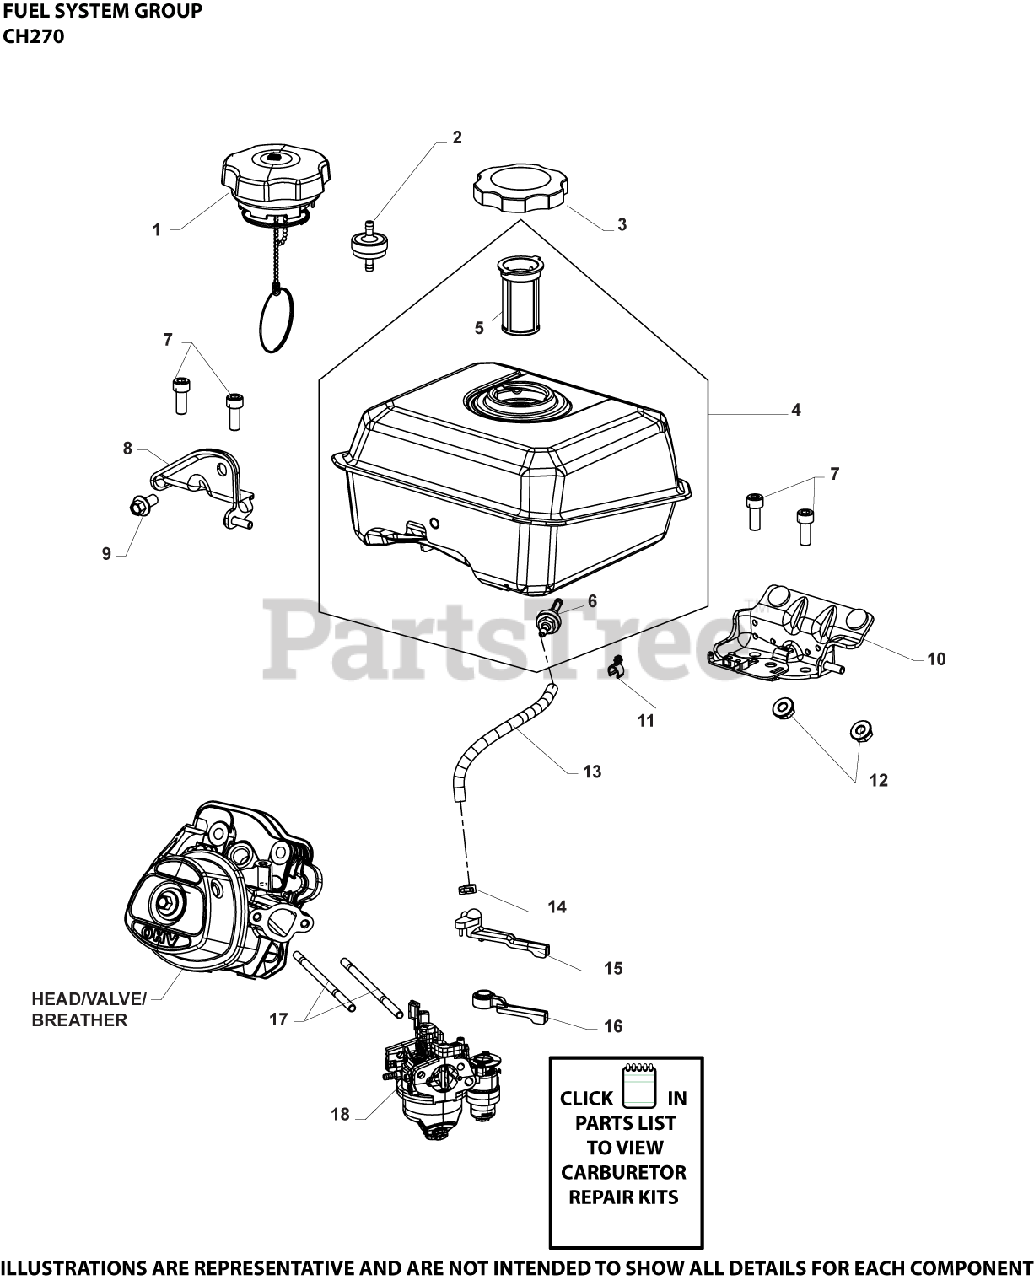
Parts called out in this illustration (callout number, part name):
3	CAP, FUEL TANK
4	TANK, ASSY FUEL
5	FILTER, FUEL TANK
6	FITTING, FUEL ASSY
7	SCREW, HEX SOCKET HD CAP (CKY)
8	BRACKET ASSY, FUEL TANK
9	SCREW, FLG 8X1.25X16
11	CLIP, FUEL HOSE
13	LINE, FUEL (10"-CUT TO LENGTH)
14	CLAMP, FUEL LINE
17	STUD, CARBURETOR
18	KIT, CARBURETOR ASSEMBLY
